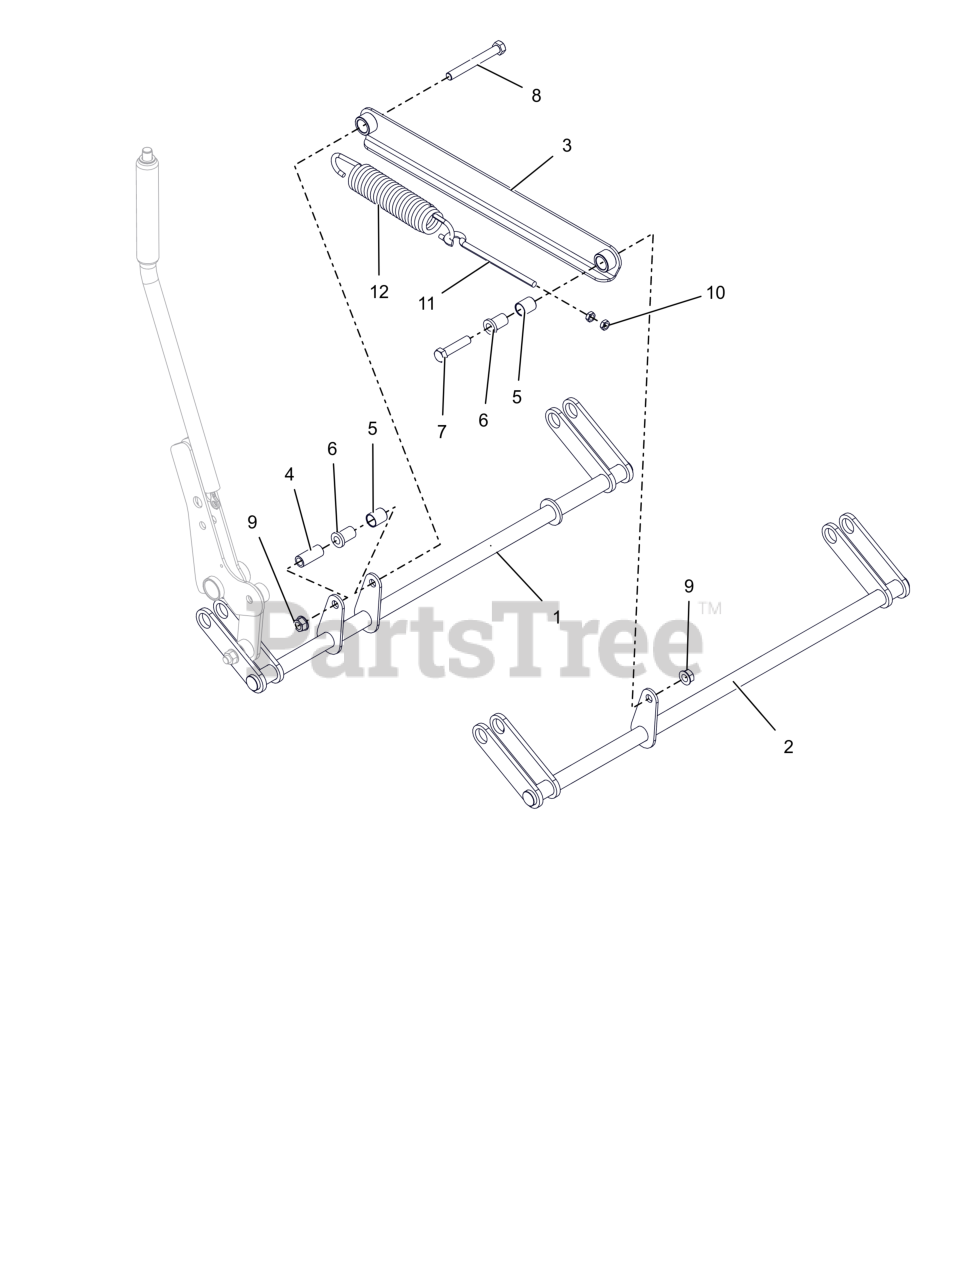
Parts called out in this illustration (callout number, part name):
1	WLDMT, DECK LIFT
2	WLDMT, FRONT DECK LIFT (BLACK)
3	LINK, DECK LIFT
4	BSHG, FLANGE .515 X .750 X 1.544 X 1.000
5	BRG, .750 X .875 X 1.000
6	BSHG-FLG .515X.746X1.290X1.000
7	BLT, HEX .50-13X2.25 G5 ZCC
8	BLT, HEX 0.5-13X4.25 GR5 ZCC
9	NUT-LK-CTR-FLG .500-13 GG ZCC
10	NUT-JAM .375-16 G2 ZCC
11	BOLT, .38-16X6.00 .62 DIA EYE
12	SPRG, EXTENSION - .273X1.853X.10.125
